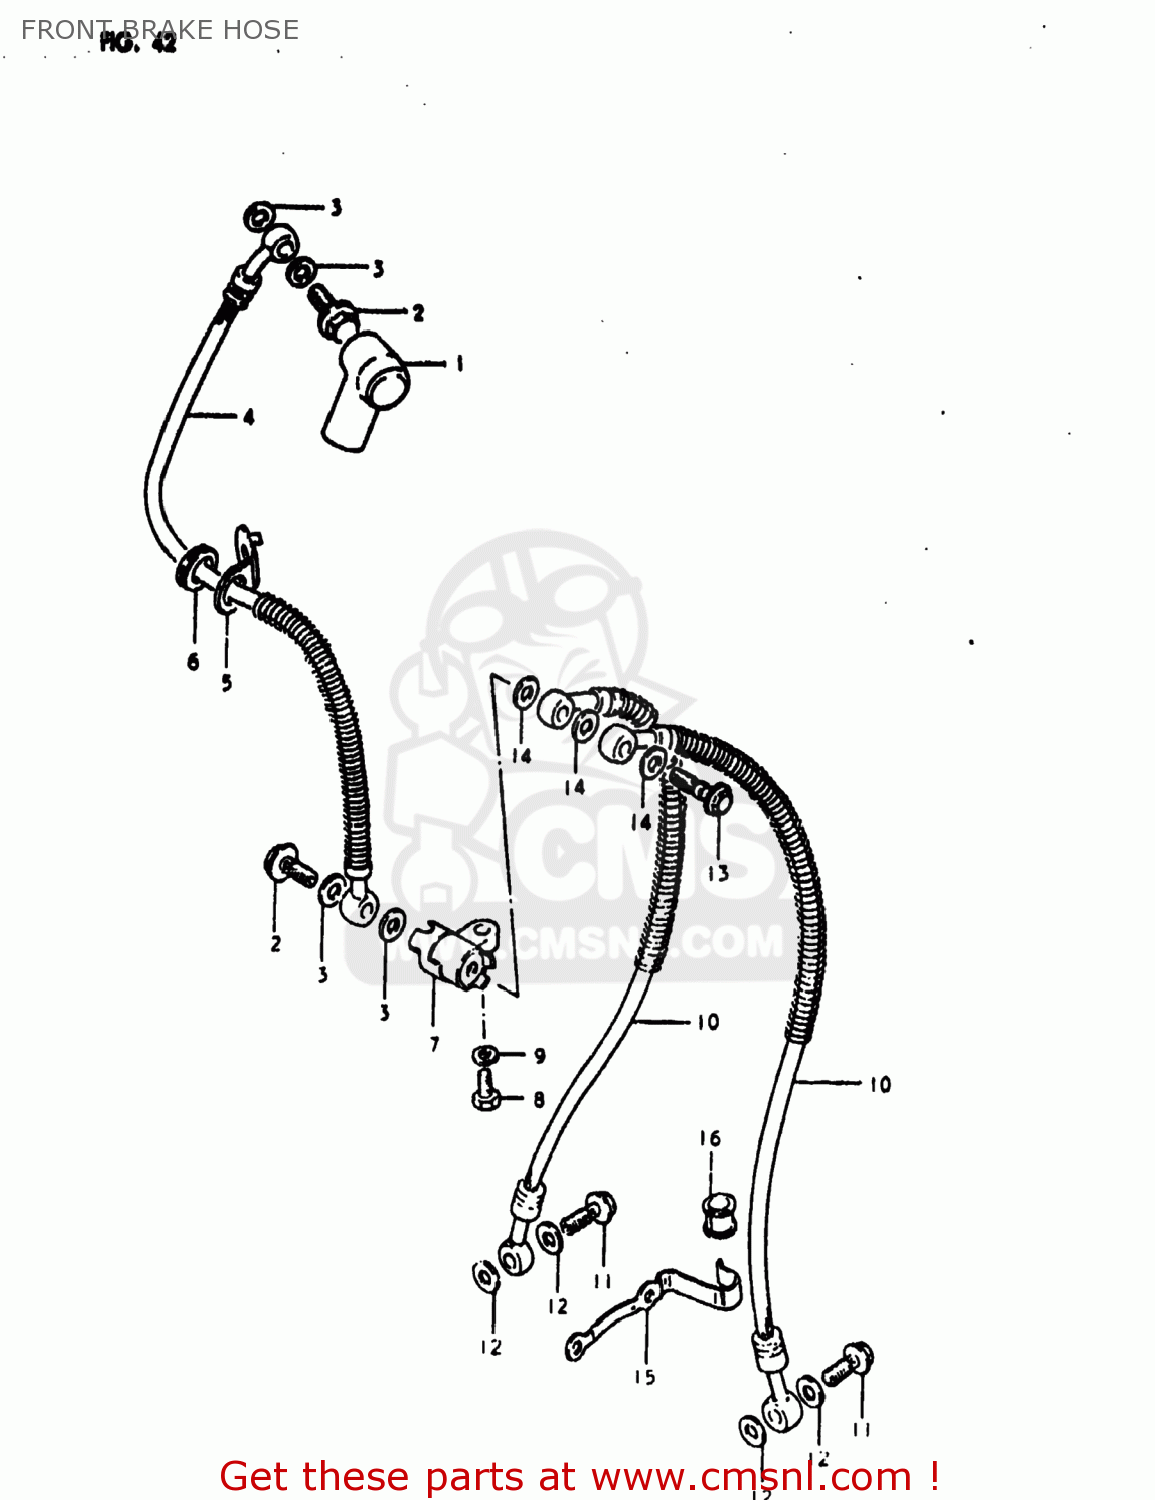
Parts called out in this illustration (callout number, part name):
1	BOOT,MASTER CYLINDER
2	BOLT,UNION
3	WASHER
4	HOSE,FRONT BRAKE
5	GUIDE,BRAKE HOSE
6	GROMMET
7	JOINT,BRAKE HOSE
8	BOLT
9	LOCK WASHER
10	HOSE,FRONT BRAKE
11	BOLT,UNION
12	WASHER
13	BOLT,UNION
14	WASHER
15	GUIDE,BRAKE HOSE NO.2
16	BUSH,BRAKE HOSE GUIDE,NO.2
